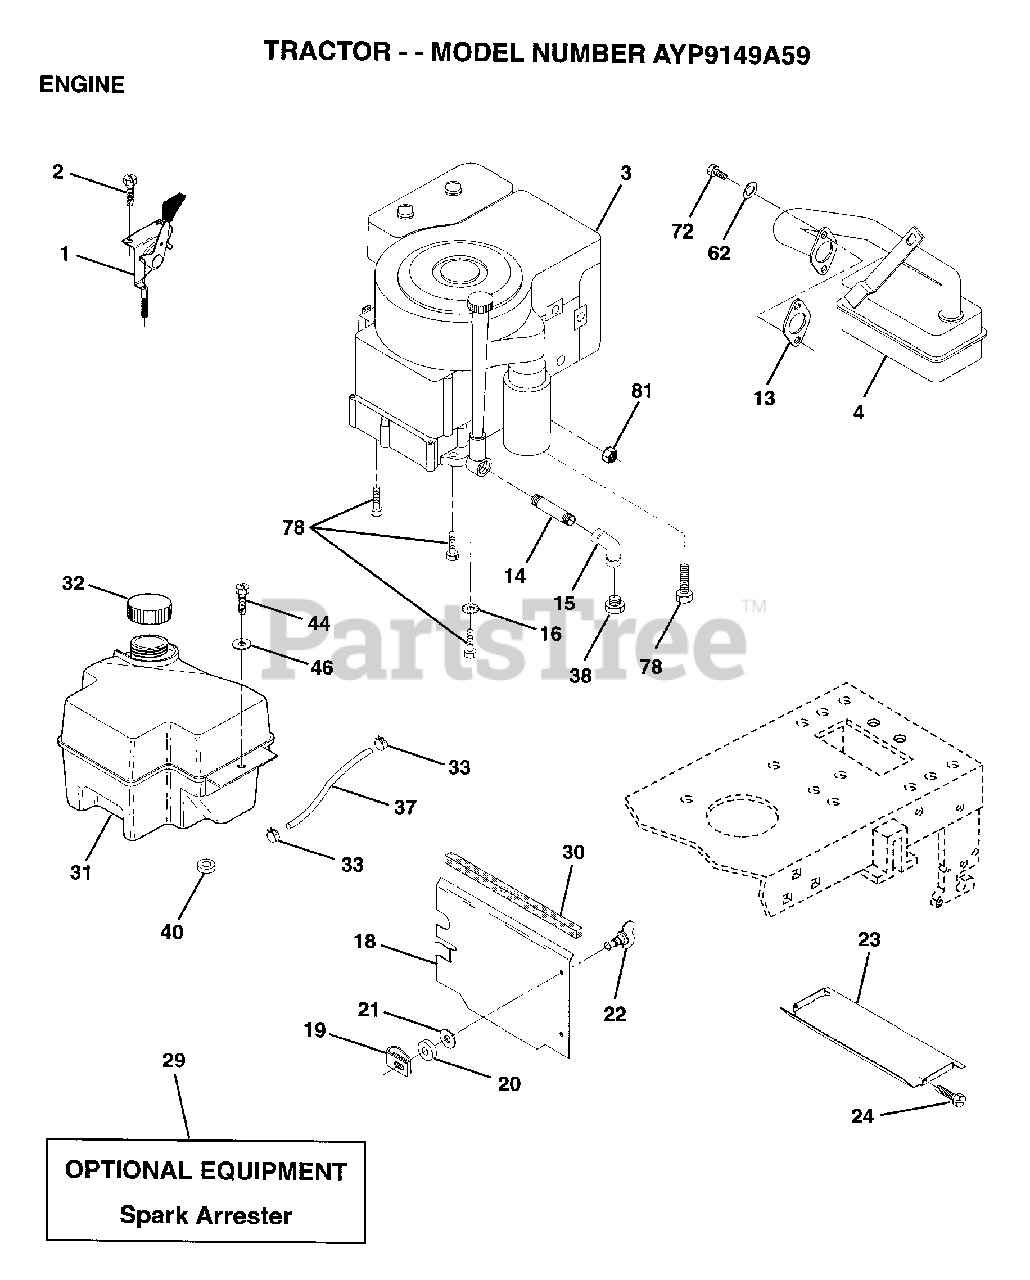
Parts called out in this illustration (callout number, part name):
1	CONTROL THROTTLE
2	SCREW LT
4	MUFFLER
14	PIPE NIPPLE
15	ELBOW
16	LOCKWASHER
18	SHIELD HEAT
19	RECEPTACLE LT
20	RETAINER LT
21	WASHER
22	STUD.1/4.TURN
24	SCREW
32	CAP ASM FUEL
33	HOSE CLAMP
37	LINE FUEL
44	SCREW HEX CRT
46	WASHER
62	LOCKWASHER
72	SCREW
78	SCREW
81	NUT
